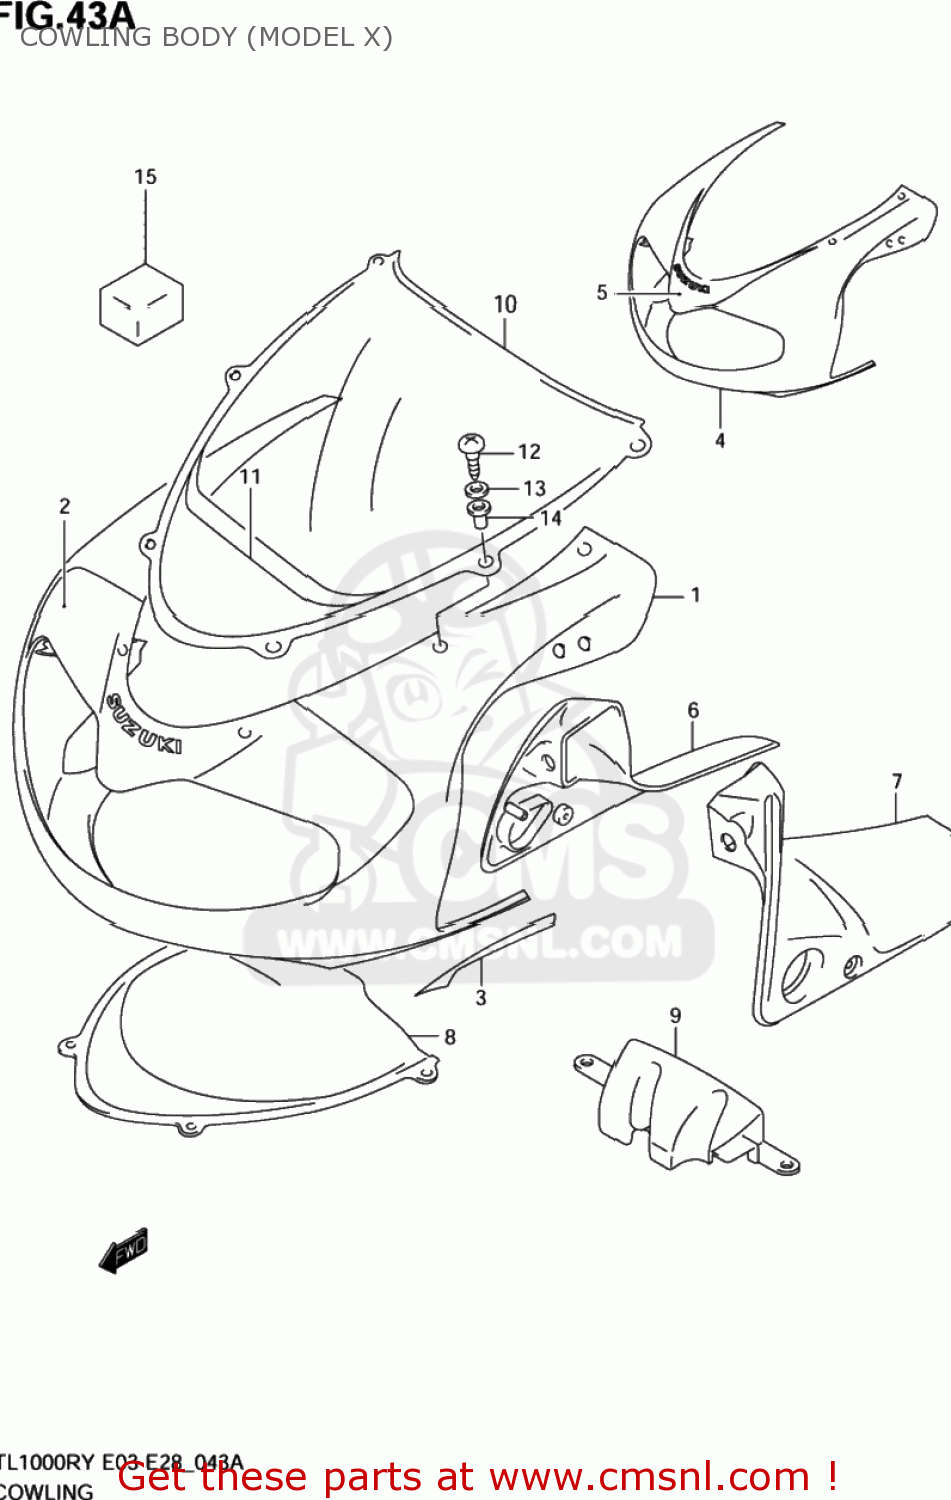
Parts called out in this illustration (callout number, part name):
1	COWLING ASSY,BODY
2	TAPE SET,FR
3	TAPE SET,SIDE LOWER (WHITE)
4	COWLING ASSEMBLY,BODY
5	TAPE SET,BODY FR
6	PANEL,SIDE,R(BLACK)
7	PANEL,SIDE,L(BLACK)
8	COVER,BODY COWLING
9	COVER,COWLING FR LWR
10	WINDSCREEN
11	TAPE,WINDSCREEN
12	SCREW(5X14)
13	WASHER
14	NUT
15	CUSHION,BODY COWLING
